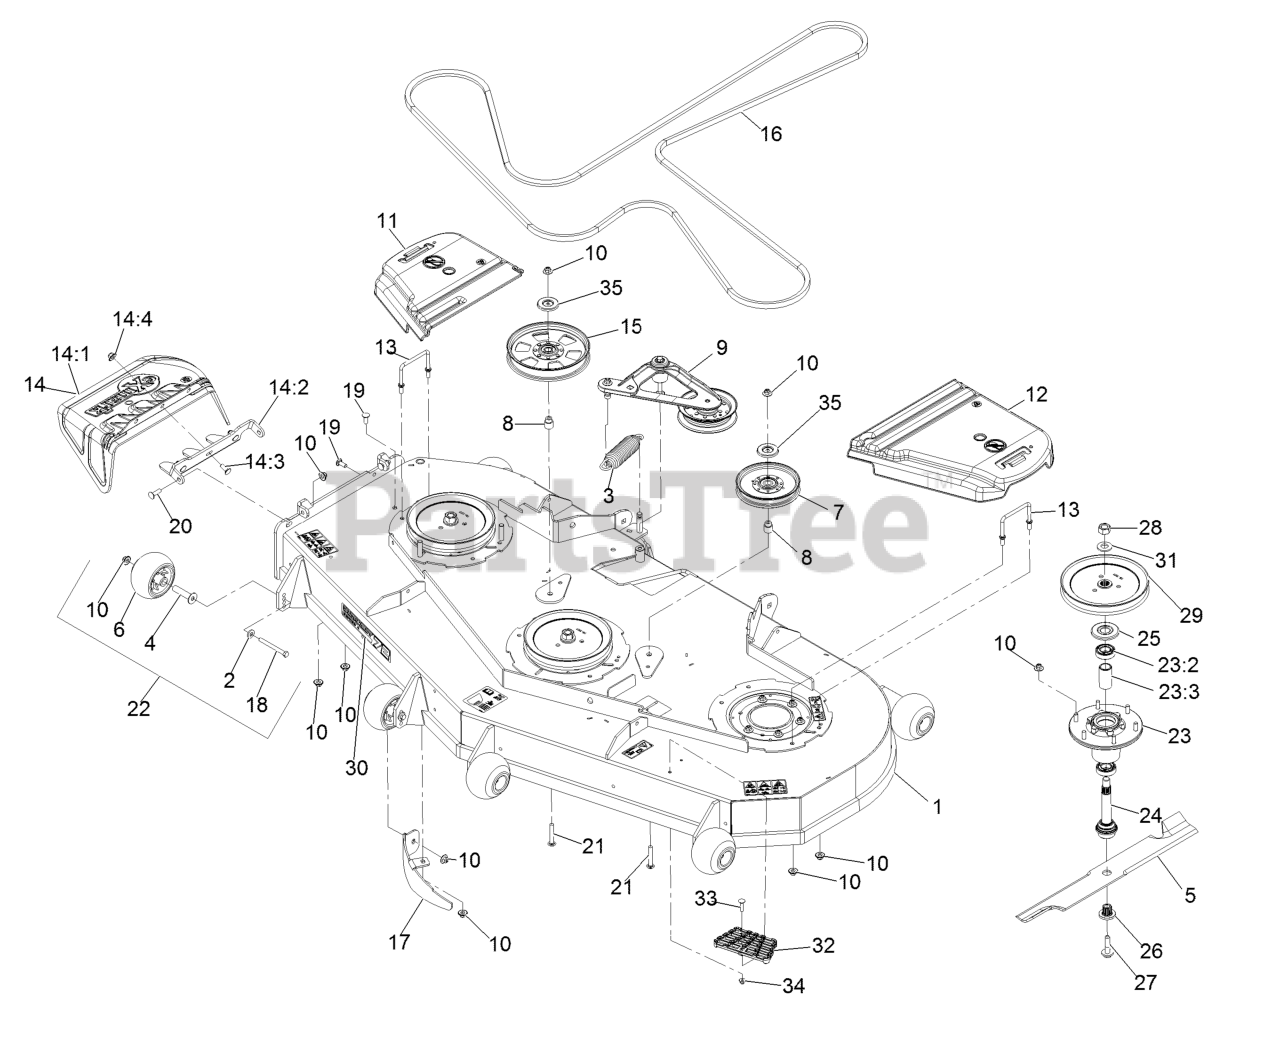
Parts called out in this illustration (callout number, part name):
1	ASM,DECK W/DECALS 724
2	WASHER-BELLEVILLE
3	SPRING-EXTENSION
4	AXLE, ROLLER
6	ROLLER-SCALP, ANTI
7	IDLER-PULLEY
8	BUSHING-IDLER
9	DECK IDLER ASM
10	Nut-Nyloc 3/8-16 Flg
11	COVER-BELT, RH
12	COVER-BELT, LH
13	WIREFORM-COVER
14	ASM,DISCHARGE CHUTE
14:1	CHUTE,DISCHARGE
14:2	BRACKET,DISCHARGE CHUTE
14:3	SCREW-CARR
14:4	Nut-Nyloc 3/8-16 Flg
15	PULLEY-IDLER, FLAT
16	BELT-V
17	BAFFLE-DOGLEG, LZ72
18	SCREW-HH 3/8-16 X 3 3/4 GR 8
19	SCREW-CARR
20	Bolt-Carriage 3/8-16 X 1 1/4
21	SCREW-CARR
22	KIT, ANTI-SCALP ROLLER
23	ASM-CUTTER HSG WITH BEARINGS
23:2	BEARING-BALL
23:3	SPACER-BEARING
24	ASM-SPINDLE AND SEAL
25	GUARD,BEARING TOP .989
26	BUSHING,SPLINED
27	SCREW,SEMS 1/2-20 X 2.19
28	NUT-HEX
29	SHEAVE,BLADE DRIVE 8.74
30	DECAL, 724
32	STEP-DECK
33	Bolt-Carriage 5/16-18 X 1 1/4
34	NUT-HF, NI
35	SHIELD-DUST
